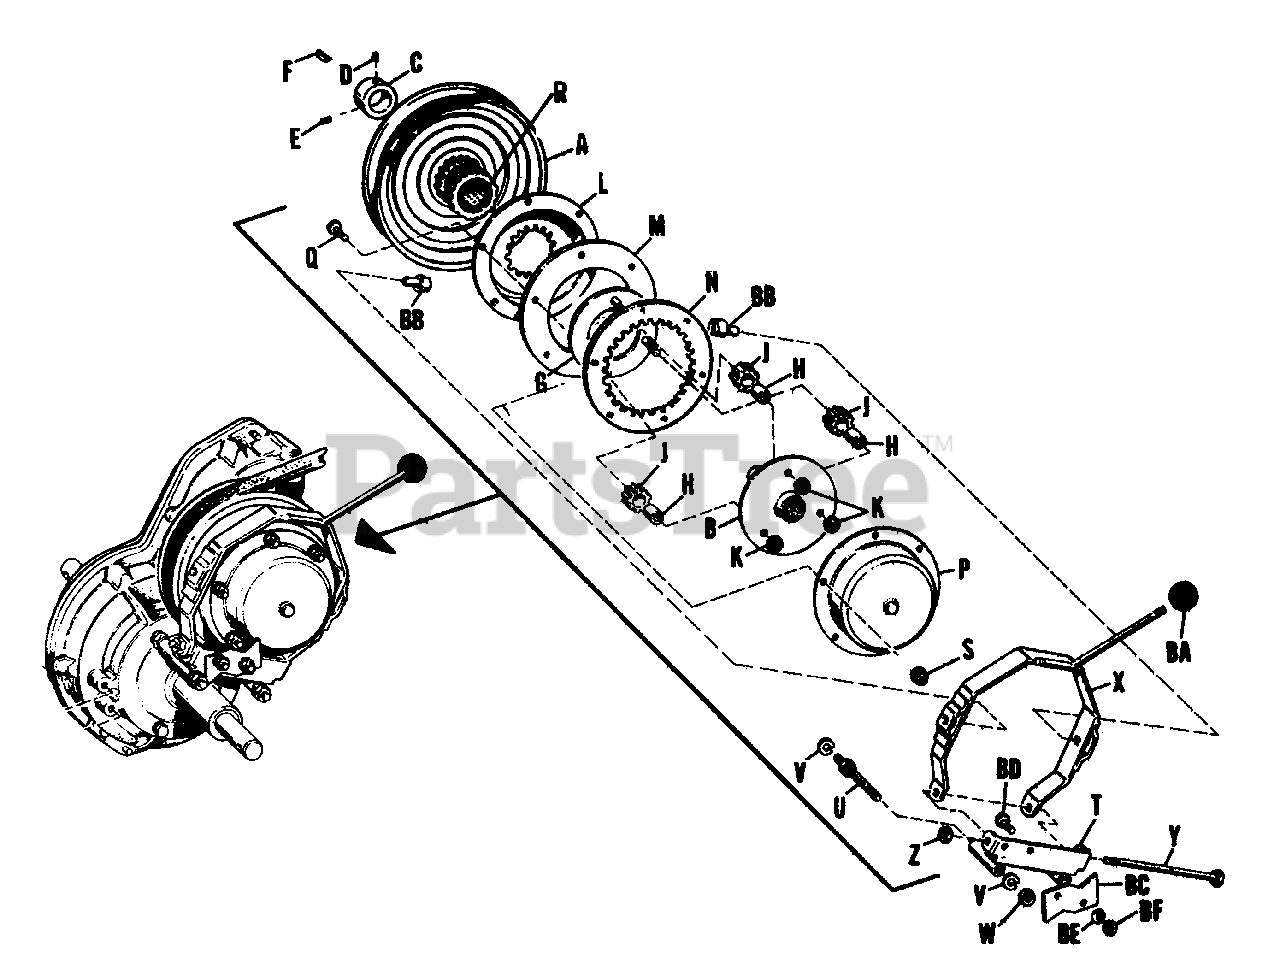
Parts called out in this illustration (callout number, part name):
A	Pulley & Gear Assembly
B	Spider & Bearing Assembly
D	Set Screw, Socket Hd., Cup Pt., 5/16"-18 x 1/2" lg.
E	Set Screw, Socket Hd., Cup Pt., 5/16"-18 x 3/8" lg.
F	Woodruff Key
G	Ring Assembly
K	Hex Nut, Full, 3/8"-16
L	Cover Assembly
M	Shift Ring
N	Gear Ring
P	Cover Assembly, Right Hand
Q	Hex Capscrew, 1/4"-20 x 5/8" lg.
R	Bushing (2 Required)
S	Nut Flange, Whiz Lock, 1/4"-20
T	Pivot Bracket Assembly
V	Lock Washer, 3/8"
W	Hex Nut, Full, 3/8"-16
X	Shift Fork Assembly
Y	Hex Capscrew, 5/16"-18 x 6-1/2" lg.
Z	Hex Nut, Full Lock, 5/16"-18
BB	Shift Pivot
BD	Hex Capscrew, 5/16"-18 x 3/4" lg.
BE	Lock Washer, 5/16"
BF	Hex Nut, Full, 5/16"-18
